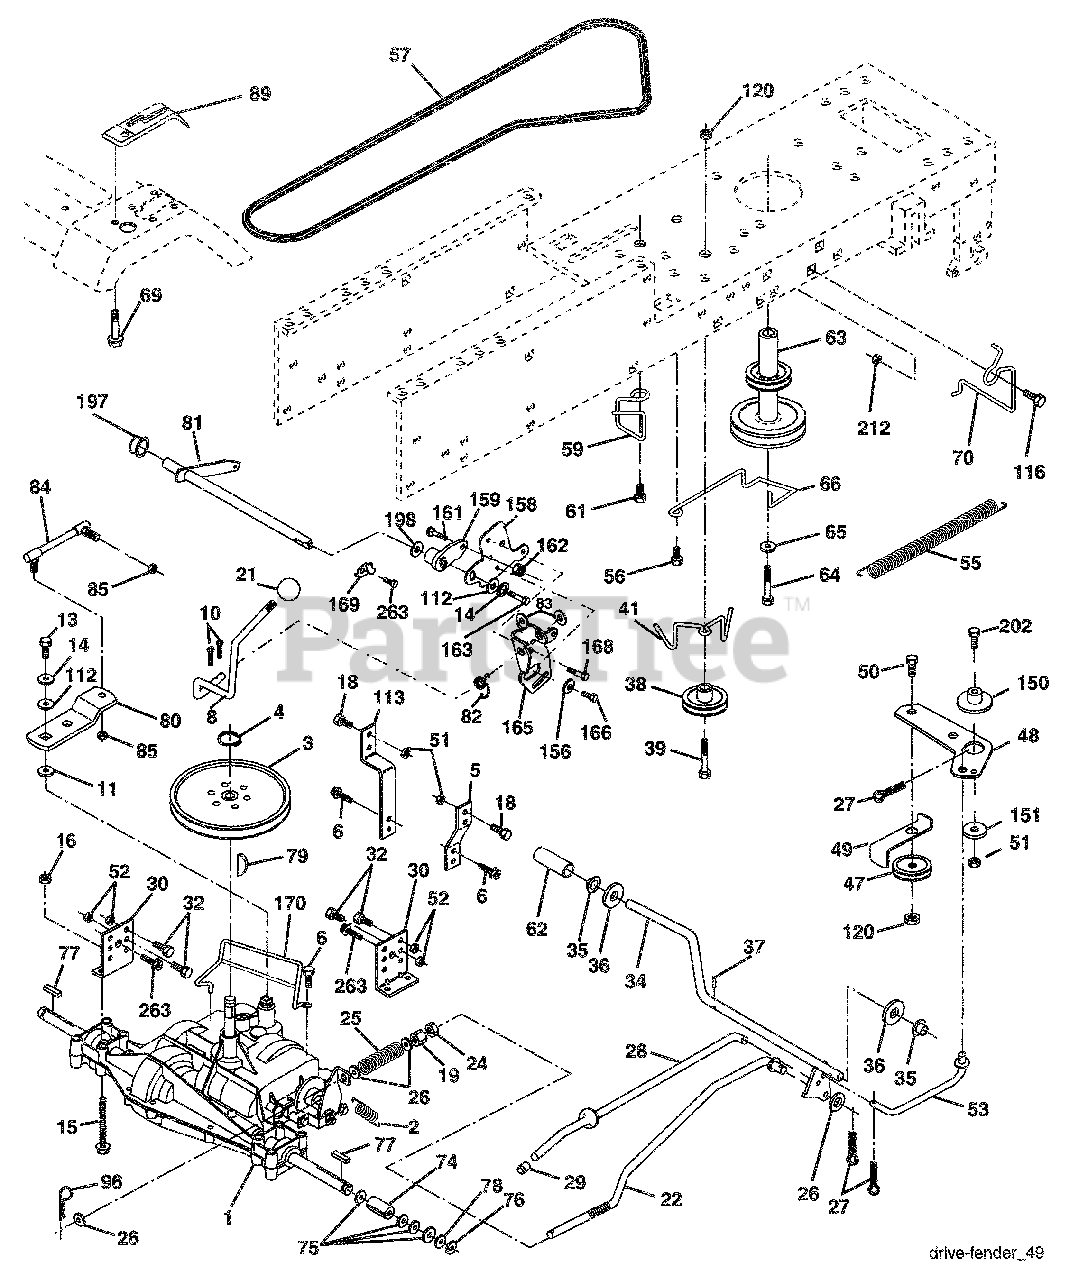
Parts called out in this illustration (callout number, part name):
2	Spring Return Brake
3	Pulley Transaxle 18"tires
4	Ring Retainer # 5100-62
5	Strap Torque 30 Degrees RH
6	Screw 5/16-18 x 3/4
8	Rod Shifter Blk
10	Pin Cotter 1/8 x 1 Cad
11	Washer Plate Shf 388 Sq Hole
13	Bolt 1/4-28 unf Gr. 8 w/Patch
14	Washer Lock Hvy Helical 1/4
15	Bolt Hex Flghd 5/16-18 Gr. 5
16	Nut 5/16-18
18	Bolt Fin Hex 3/8-16 unc x 1 Gr. 5
19	Nut lock Hex w/lns 3/8-16 Unc
21	Knob Rd 1/2-13 Plstc Thds Blk
22	Rod Brake LT
24	Nut Hex Jam 3/8-16 unc
25	Spring Rod Brake 2 00 Zinc
26	Washer 13/32 x 13/16 x 16 Ga.
27	Pin Cotter 1/8 x 3/4 Cad
28	Rod Brake Parking LT/YT
29	Cap Brake Parking Black
30	Bracket Transmission
32	Bolt Fin Hex 5/16-18 x 3/4
34	Shaft Asm Pedal Foot Nibbed
35	Bearing Nylon Blk 629 Id
36	Washer 21/32 x 1 x 16Ga.
37	Pin Rol! 3/16 x 1"
38	Pulley Composite Flat
39	Bolt 3/8-16 x 2-3/4
41	Keeper Belt Idler
47	Pulley idler V Groove Plastic
48	Bellcrank Clutch Grnd Drv STL
49	Retainer Belt Style Spring
50	Bolt Carr Sh 3/8-16 x 1-1/2 Gr. 5
51	Nut Crownlock 3/8-16 unc
52	Nut Crownlock 5/16-18 unc
53	Link Clutch 7 66
55	Spring Return Clutch 6 75
56	Screw 3/8-16 x 1-1/4
57	V-Belt Ground Drive 95
59	Keeper Belt Chassis Span Ctr
61	Screw 3/8-16 x .875
62	Cover Pedal Blk Round
63	Engine Pulley LT/YT
64	Bolt Hex 7/16-20 x 4 Gr. 5
65	Washer Lock Hvy Hlcl Spr 7/16
66	Keeper Belt Engine
69	Screw 1/4 x 1/2 unc
70	Guide Belt Mower Drive RH
74	Spacer Axle
75	Washer 25/32 x 1 1/4 x 16 Ga.
76	E-ring #5133-75
77	Key Square 2 0x1845/1865
78	Washer 25/32 x 1-5/8 x 16 Ga.
79	Key Woodruff
80	Arm Shift Transaxle
81	Shaft Asm Cross Taper
82	Spring Torsion Shift
83	Washer 17/32 x 3/4 x 16 Ga.
84	Link Transaxle
85	Nut Lock Center 1/4-28
89	Console Shift
96	Retainer Spring 1"
112	Washer 9/32 x 3/4 x 10 Ga.
113	Strap Torque 90 Degrees LH
116	Bolt Rdhd Sq Neck 3/8-16 x 1
120	Nut Lock Flg 3/8-16
150	Spacer Retainer Lt
151	Washer 13/32 x 2 x 10 Ga.
156	Washer Srrrtd 5/16 ID x 1.0 x .125
158	Bracket Shift Mount
159	Hub Shift
161	Bolt 1/4-20 x 3/4 Gr. 5
162	Nut Crownlock 1/4-20 unc
163	Bolt Hex Fin 1/4-20 unc x 1 Gr. 5
165	Bracket Pivot Lever
166	Screw 5/16-18 x 5/8
168	Bolt Shoulder 5/16-18 x .561
169	Plate Fastening
170	Keeper, Belt Transaxle
197	Nyliner Snap-In 5/8
198	Washer Nylon
202	Bolt Carr Sh 3/8-16 x 1-3/4 Gr. 5
212	Nut Hex Flg Lock
263	Screw 3/8-16 x 3/4
